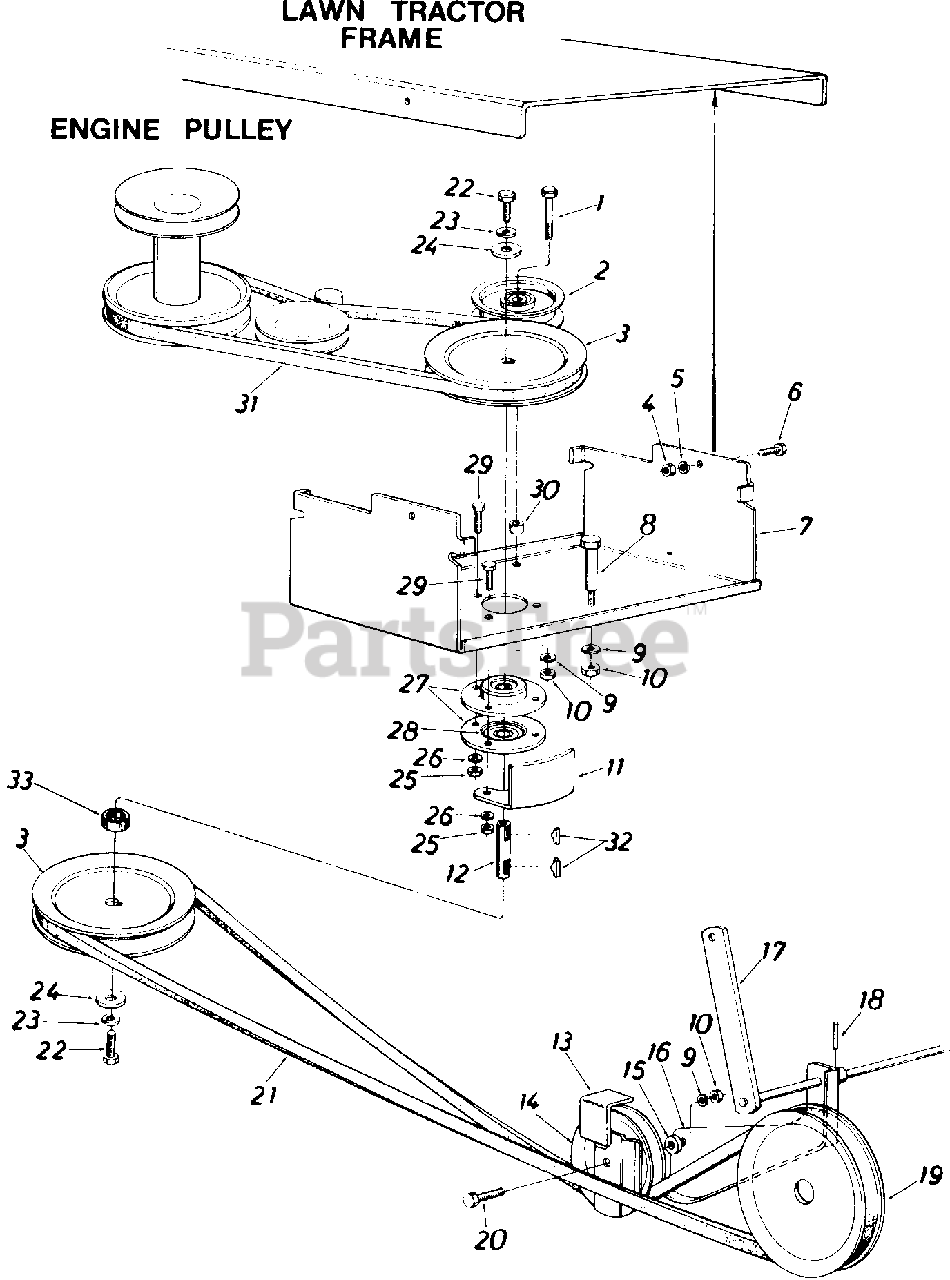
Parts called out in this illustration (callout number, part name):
1	Hex Bolt 3/8-16 x 2.00" Lg.*
2	Fl.-Idler w/Flanges 3-3/4" O.D.
3	5/8" "V"-Pulley.790" I.D. x .650" O.D.
4	Hex Nut 3/8-24 Thd.*
5	L.-Wash. 3/8" I.D. Heavy Duty
6	Hex Bolt 3/8-24 x .88" Lg.*
7	Carriage Bracket
8	Shoulder Bolt .498" Dia. x 1 .64
9	L.-Wash. 3/8" I.D.*
10	Hex Nut 3/8-16 Thd.*
11	Belt Guard
12	Shaft. 787" Dia. x 2.56" Lg.
13	Belt Separator Plate
14	Fl.-ldler w/Flanges 3.25" O.D.
15	Fl.-Wash. .406" I.D. x 1.25" O.D. x .164
18	Spring Pin Roll 3/16" Dia. x 1.50" Lg.
19	5/8" V-Pulley 1.50" I.D. x 6.50" O.D.
20	Hex Bolt 3/8-16 x 1.75" Lg.*.
21	V-Belt 1/2" x 95.0" Lg.
22	Hex Bolt 5/16-18 x .88" Lg. Spec.
23	L.-Wash. 5/16" I.D.*
24	Fl.-Wash. .344" I.D. x 1.125" O.D. x .125
25	Hex Nut 5/16-18 Thd.*
26	L.-Wash. 5/16" I.D.*
27	Bearing Housing 1.85" I.D.
28	Ball Bearing .787" I.D. x 1.85" O.D.
29	Hex Sems Bolt 5/16-18 x .75"
30	Spacer
31	Belt 1/2" Wide x 52" Long
32	Hi-Pro Key 3/16" x 5/8"
33	Spacer-.80" I.D. x 1.0" O.D.
